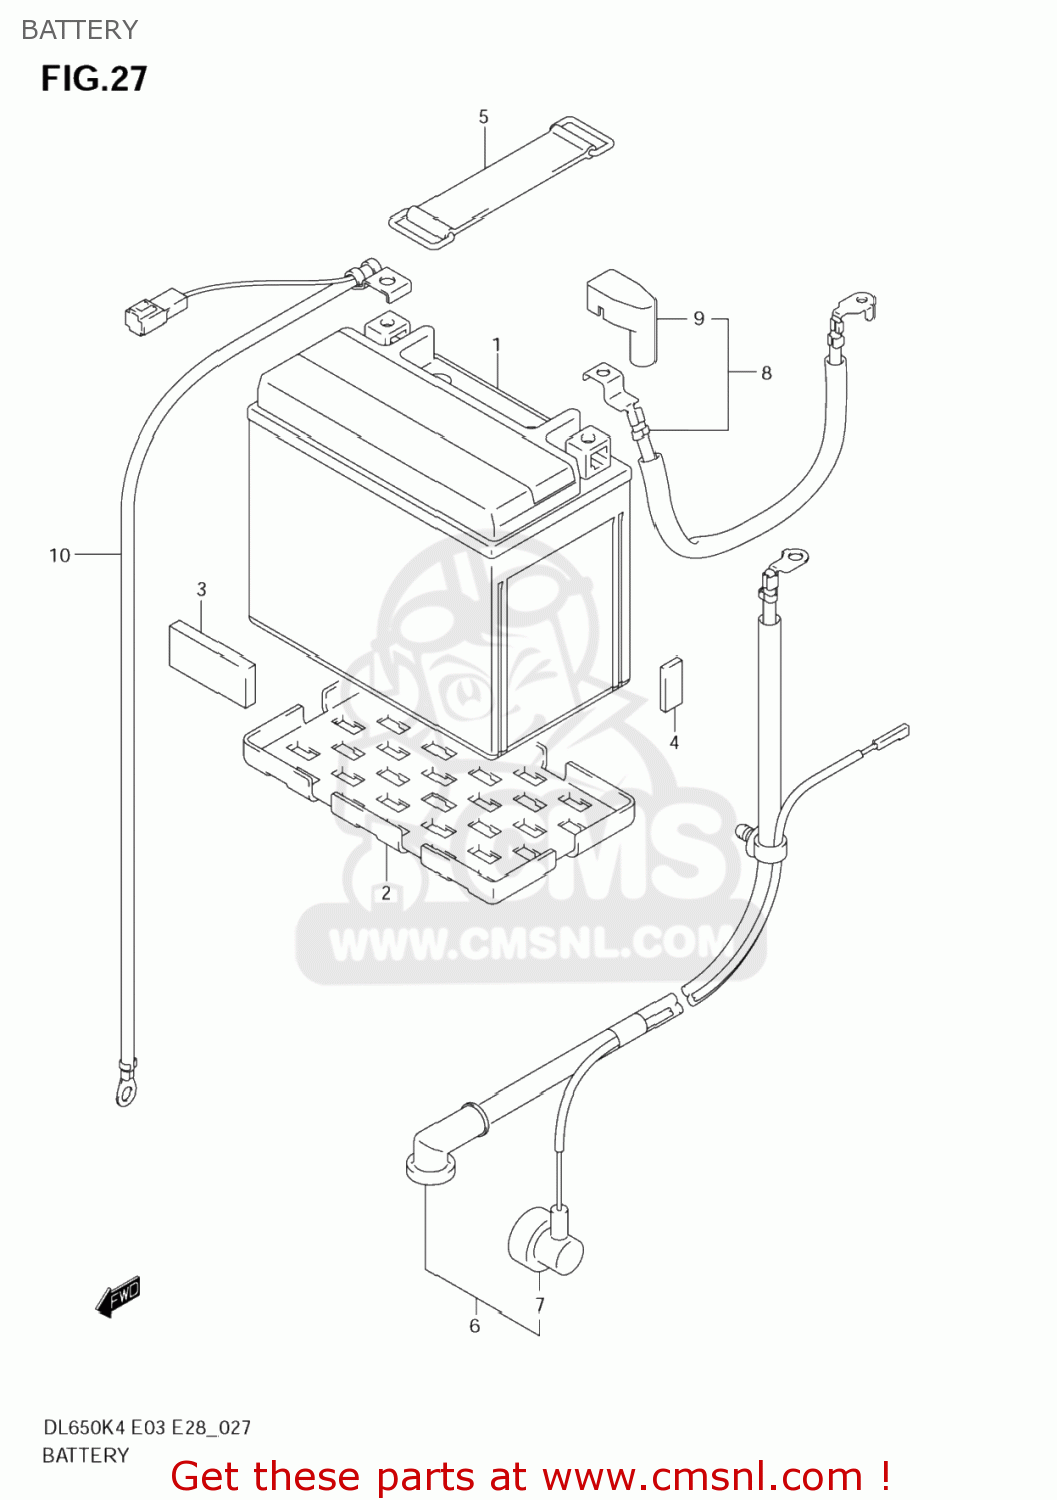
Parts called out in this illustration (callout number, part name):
1	BATTERY ASSY(YTX12-BS,12V10AH)
2	PROTECTOR,BATTERY
3	PROTECTOR,BATTERY(70X100X6)
4	PROTECTOR(170X95X3.0)
5	BAND
6	WIRE,STARTER MOTOR LEAD
7	CAP,OIL PRESSURE SWITCH
8	WIRE,BATTERY PLUS LEAD
9	CAP,BATTERY PLUS LEAD
10	WIRE,BATTERY MINUS LEAD
